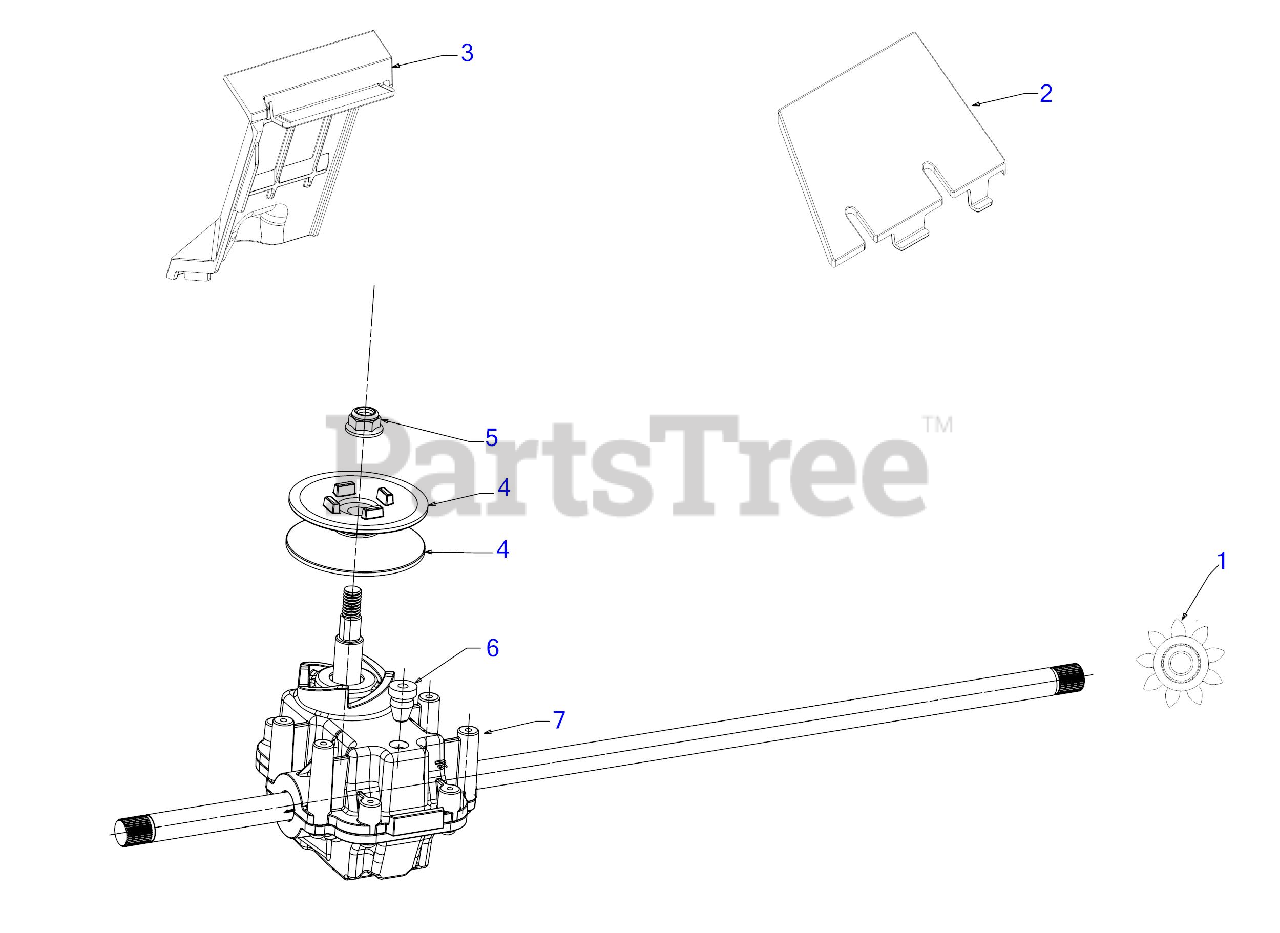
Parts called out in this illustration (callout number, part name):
1	SPUR GEAR 9T
2	TRANSMISSION COVER (REAR)
3	TRANSMISSION COVER (FRONT)
4	HALF PULLEY 2.50 OD
5	FLANGE LOCK NUT 5/16-18
6	RUBBER PLUG
7	TRANSMISSION ASSEMBLY
